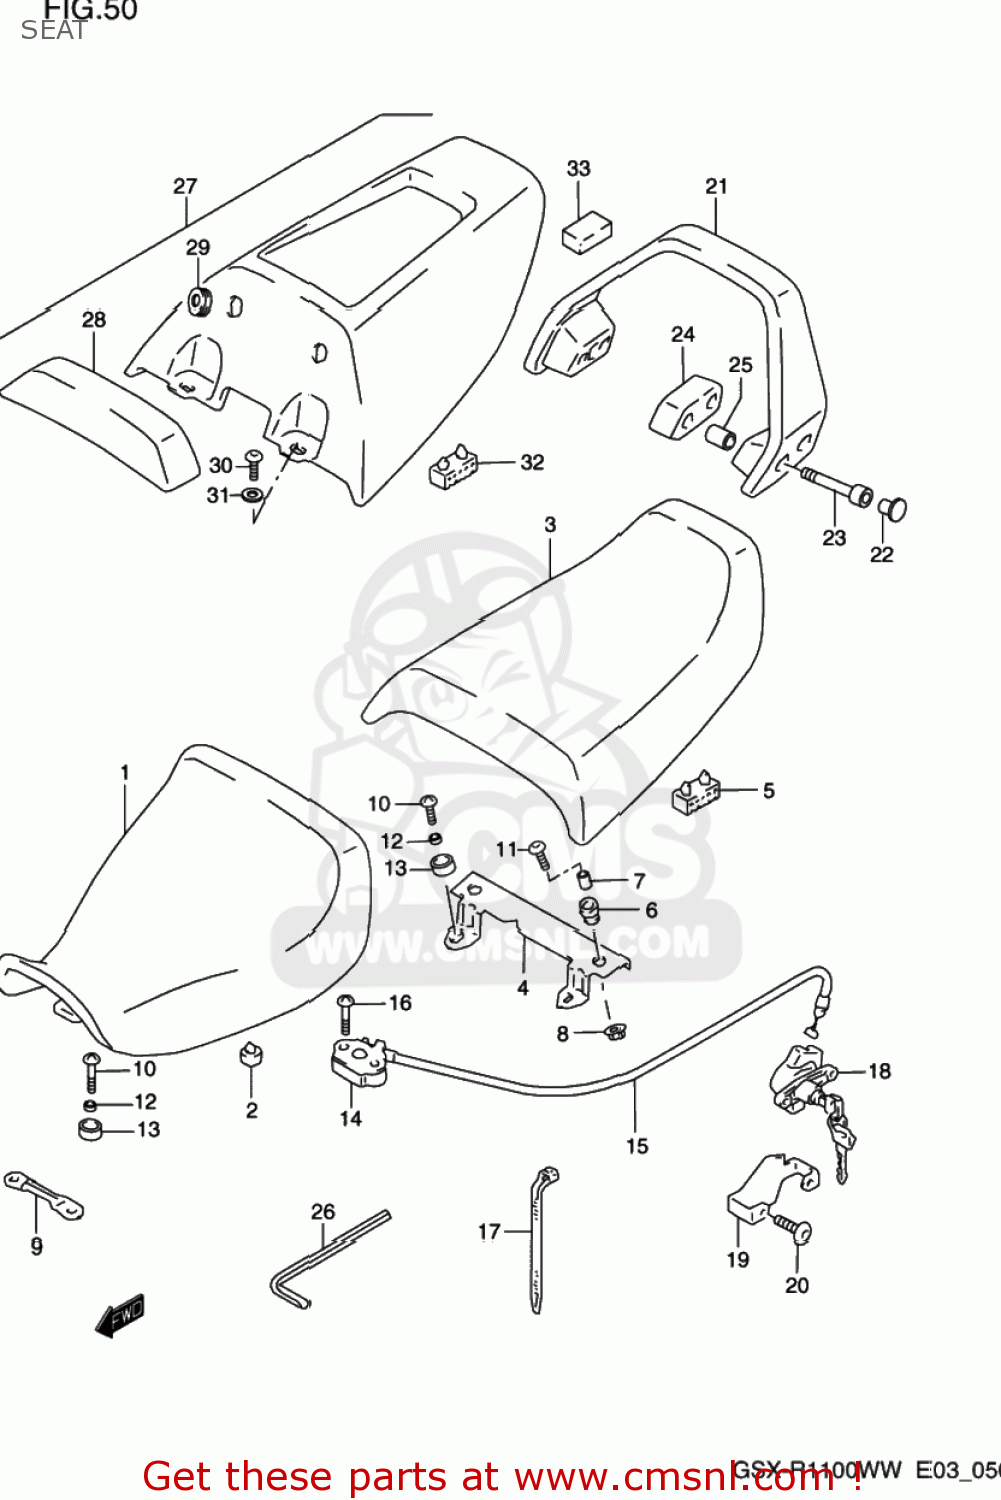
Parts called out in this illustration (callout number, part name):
1	SEAT ASSY
2	CUSHION
3	SEAT ASSY,PILLION
4	PLATE,FR HOOK
5	CUSHION,SEAT(40X20X15)
6	CUSHION
7	SPACER
8	NUT
9	PLATE,SEAT FR HOOK
10	SCREW
11	SCREW(6X12)
12	SPACER (6.8X10X4.7)
13	CUSHION,TAIL COVER UPR
14	BRACKET,SEAT SUPPORT RR
15	CABLE,SEAT LOCK
16	SCREW
17	CLAMP L:165
18	LOCK SET,SEAT
19	PLATE,SEAT LOCK GUARD
20	SCREW(6X12)
21	HANDLE,PILLION RIDER
22	CAP(OD:14.5)
23	BOLT
24	CUSHION,PILLION RIDER HANDLE,R
25	SPACER (8.5X16X37)
26	SPANNER,HEXAGON(4)
27	BOX SET,SEAT TAIL
28	BACKREST,SEAT(BLACK)
29	CUSHION
30	SCREW(6X16)
31	WASHER(6.5X20X1.6)
32	CUSHION,SEAT(40X20X15)
33	PROTECTOR,TAIL BOX
